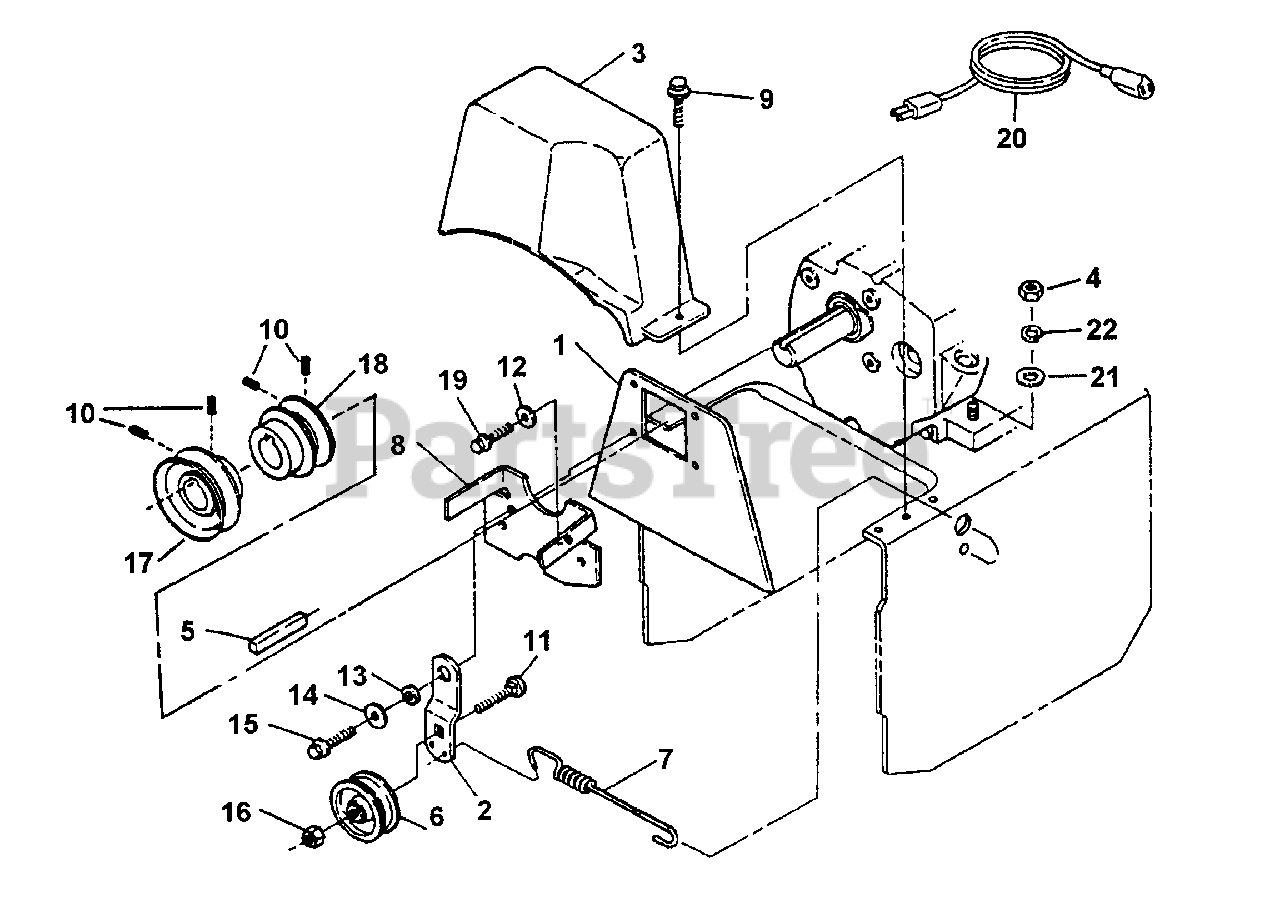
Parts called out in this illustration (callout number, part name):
1	GUARD, Engine
2	ARM, Idler
3	COVER, Belt
4	NUT, 5/16-18 Hex, Grade B or 5
5	KEY, 1/4 x 2" Square
6	IDLER
7	SPRING, Idler
8	FINGER, Belt
9	SCREW, 1/4-20 x 1/2" Hex Washer Self-Tap
10	SCREW, 5/16-18 x 5/16" Socket Head Set
11	BOLT, 3/8-16 x 1-1/2" Square Neck Carriage, Grade 2
12	WASHER, 5/16 Flat
13	SPACER
14	WASHER, 3/8" Flat
15	SCREW, 5/16-24 x 7/8" Hex Head Cap, Grade 5
16	NUT, 3/8-16 Hex Top Lock
17	PULLEY, Blower
18	PULLEY, Traction
19	SCREW, 5/16-24 x 3/4" Hex Head Cap, Grade 5
20	CORD, 10' Extension for 110V
21	WASHER, 5/16 Flat
22	WASHER, 5/16 Split Lock
